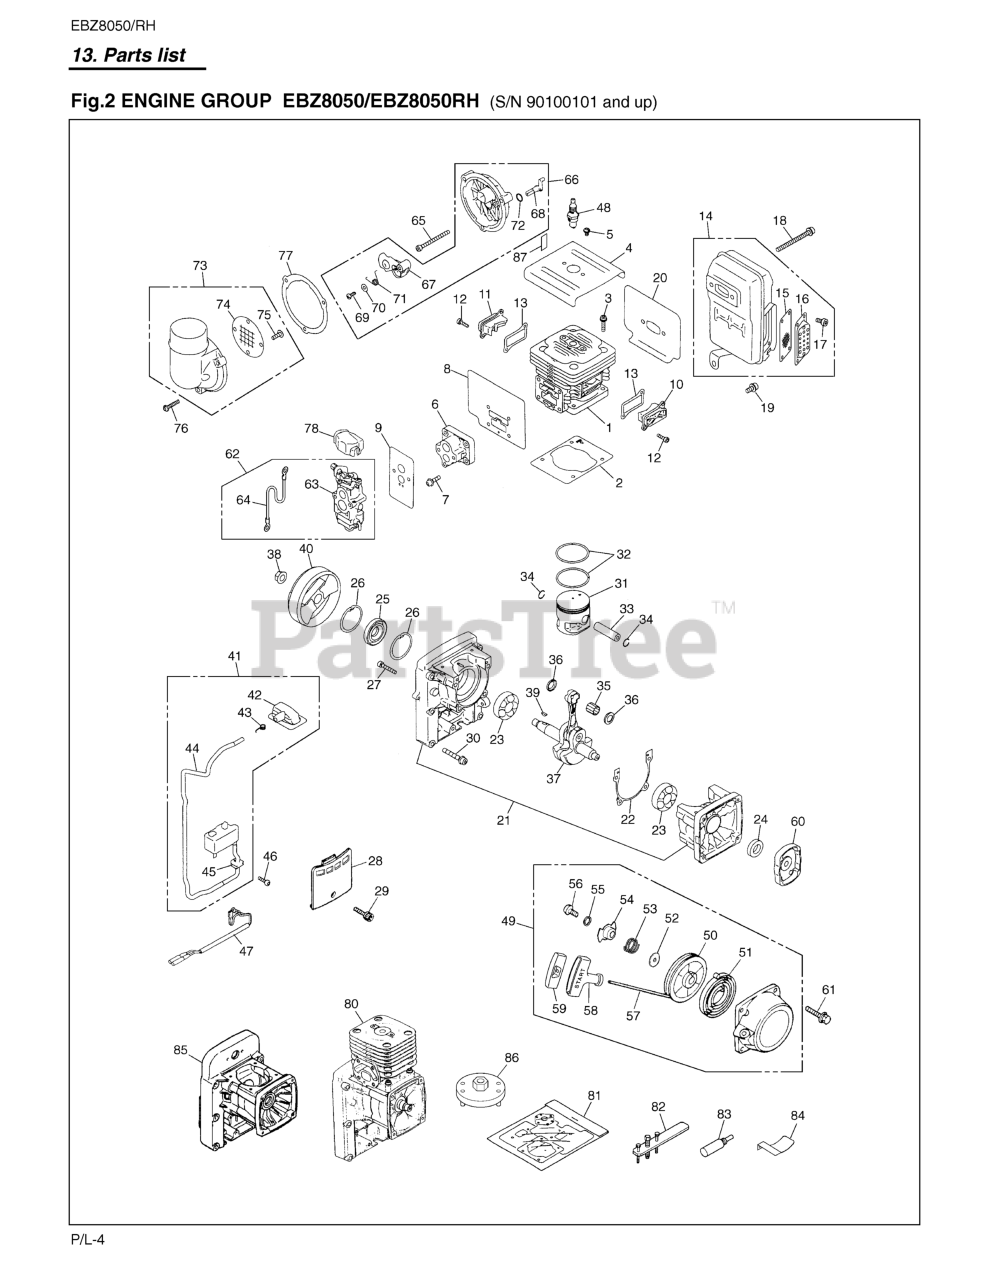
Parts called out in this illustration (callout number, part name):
1	CYLINDER (RPLS 12A2)
2	GASKET, BASE
3	BOLT
4	PLATE, CYL
5	SCREW TORX
6	INSULATOR
7	BOLT
8	GASKET, INSULATOR
9	GASKET, CARB.
10	COVER, TR-S
11	COVER,TR-F
12	BOLT TORX
13	GASKET, TR
14	Muffler Assy
15	Arrester
16	Diffuser
17	Bolt
18	BOLT TORX
19	BOLT
20	GASKET, MUFFLER
21	CRANKCASE-CASE
22	GASKET, CASE
23	BEARING
24	SEAL
25	SEAL
26	SNAP RING
27	BOLT
28	COVER
29	BOLT TORX
30	BOLT TORX
31	PISTON
33	PIN
34	SNAP RING
35	BEARING
36	WASHER
37	CRANKSHAFT-C
38	NUT
39	KEY
40	ROTOR
41	COIL ASSY
42	CAP
43	SPRING
44	TUBE
45	GROMMET
46	BOLT TORX
47	CORD COMP
48	SPARK PLUG
49	RECOIL ASSY (RPLS -7511)
50	REEL (REPLACES -75C1)
51	SPRING
52	WASHER (REPLACES -75M0)
53	SPRING, FRICTION (RPLS. -75L1)
54	PLATE, FRICTION (RPLS. -75K1)
55	WASHER (REPLACES -75W0)
56	SCREW
57	ROPE
58	KNOB
59	COVER KNOB
60	PULLEY (RPLS 848-H00-7520)
61	BOLT, TORX
62	CARBURETOR SET
63	CARBURETOR-A (WYA-44)
64	Cord
65	BOLT
66	CHOKE CUP ASSY
67	PLATE, CHOKE
68	LEVER
69	SCREW
70	WASHER
71	SPRING
72	O-RING
73	COVER ASSY. (REPLACES -8340)
74	SCREEN
75	SCREW
76	SCREW
77	GASKET,CUP
78	COVER
80	SHORT BLOCK
81	GASKET KIT
82	PULLER ASSY
83	STOPPER
84	GAUGE
85	CRANKCASE-A
86	PULLER
87	LABEL, CHOKE
